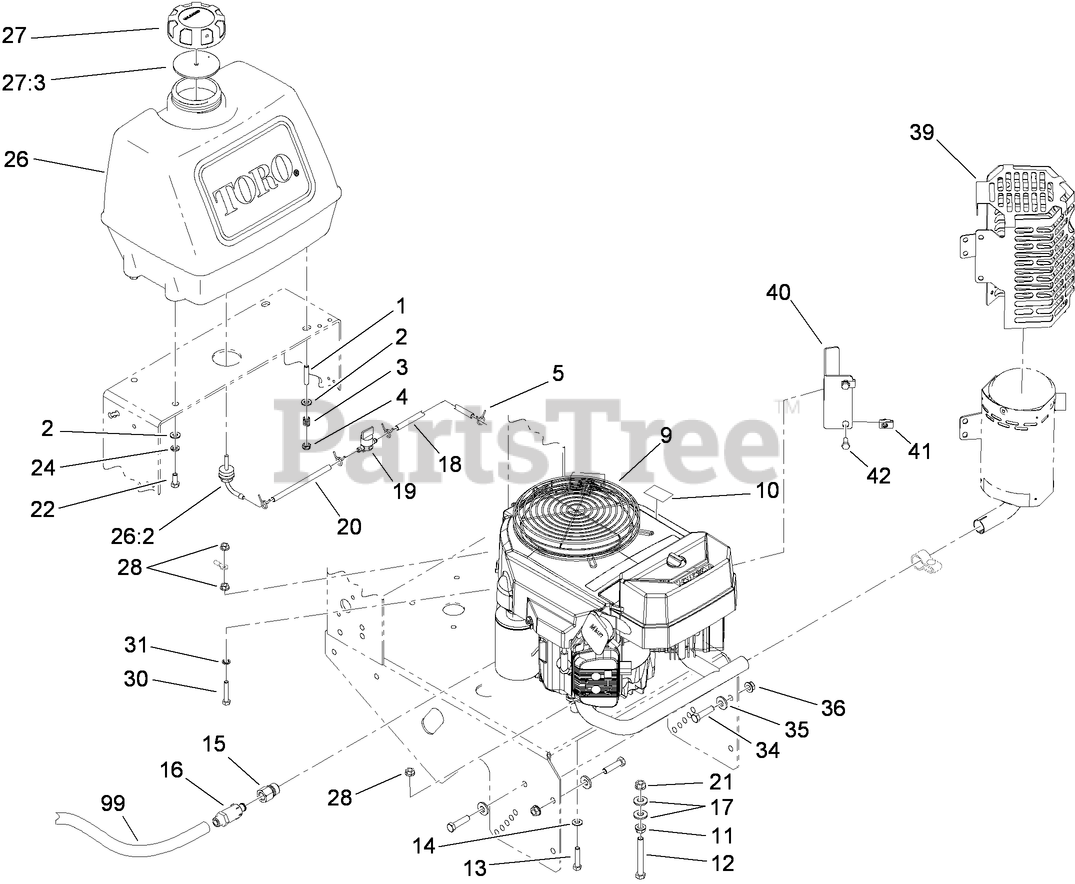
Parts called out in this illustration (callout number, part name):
2	WASHER-PLAIN
3	SPRING-TANK, FUEL
4	NUT-LOCK, NI
10	DECAL-WARNING
11	NUT-HHF, WHIZ
12	SCREW-HH
13	SCREW-HH
14	WASHER-SPRING
15	Adapter
16	VALVE-DRAIN, OIL
17	WASHER-BELLEVILLE
18	HOSE-FUEL
19	VALVE-FUEL
20	HOSE-FUEL
21	NUT-HF
22	SCREW-HH
24	WASHER-LOCK
26	FUEL TANK ASM
26:2	FITTING-FUEL, BULKHEAD
27	GAS CAP ASM
27:3	GASKET-CAP, GAS
28	NUT-HF
30	SCREW-HH
31	WASHER-LOCK, INTERNAL
34	SCREW-HH
35	WASHER-BELLEVILLE
36	NUT-HHF, WHIZ
39	MUFFLER SHIELD ASM
40	BRACKET-MUFFLER
41	NUT-U
42	SCREW-HH
99	HOSE-DRAIN, OIL
